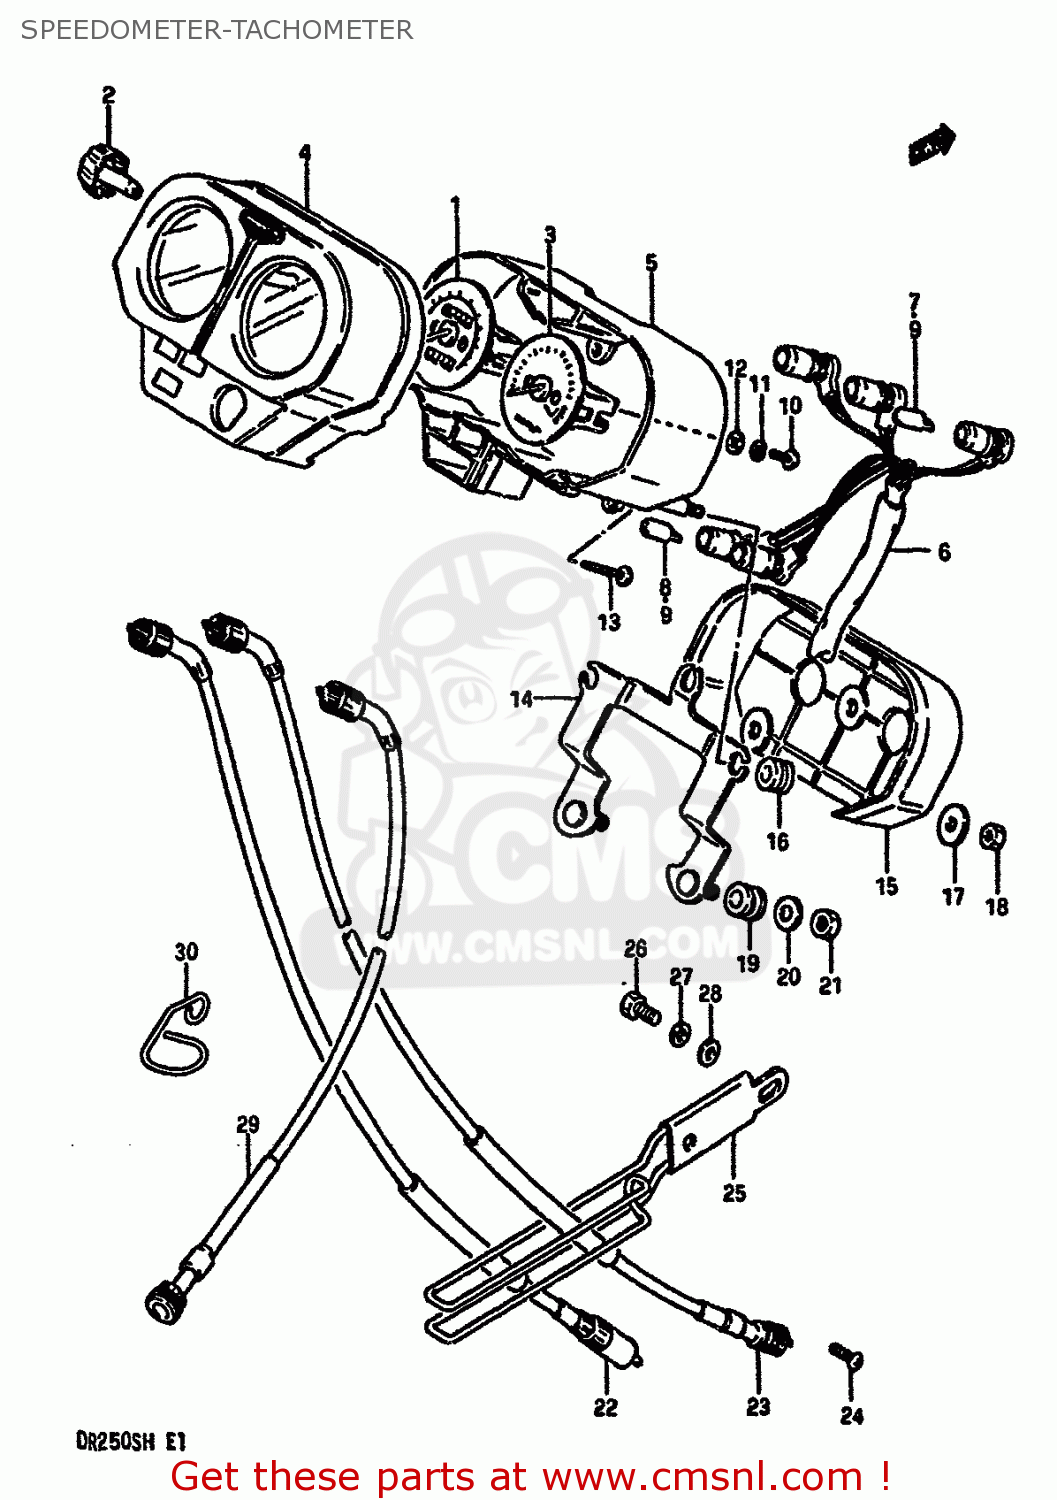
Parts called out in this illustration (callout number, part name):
1	SPEEDOMETER
2	KNOB,TRIP
3	TACHOMETER
4	HOOD, METER
5	CASE,INNER
6	SOCKET
7	BULB(6V1.7W,STANLEY,A61A)
8	BULB(6V,3W)
9	BULB(12V3.4W,T10)
10	SCREW 4X10
11	LOCK WASHER
12	WASHER
13	SCREW
14	BRACKET
15	COVER
16	CUSHION
17	WASHER (5.5X16X1.2)
18	NUT
19	CUSHION
20	WASHER
21	NUT
22	CABLE ASSY,SPE
23	CABLE,SPEEDOMETER
24	SCREW
25	GUIDE,CABLE
26	BOLT 8X12
27	LOCK WASHER
28	WASHER
29	CABLE ASSEMBLY,TACHOMETER
30	GUIDE
